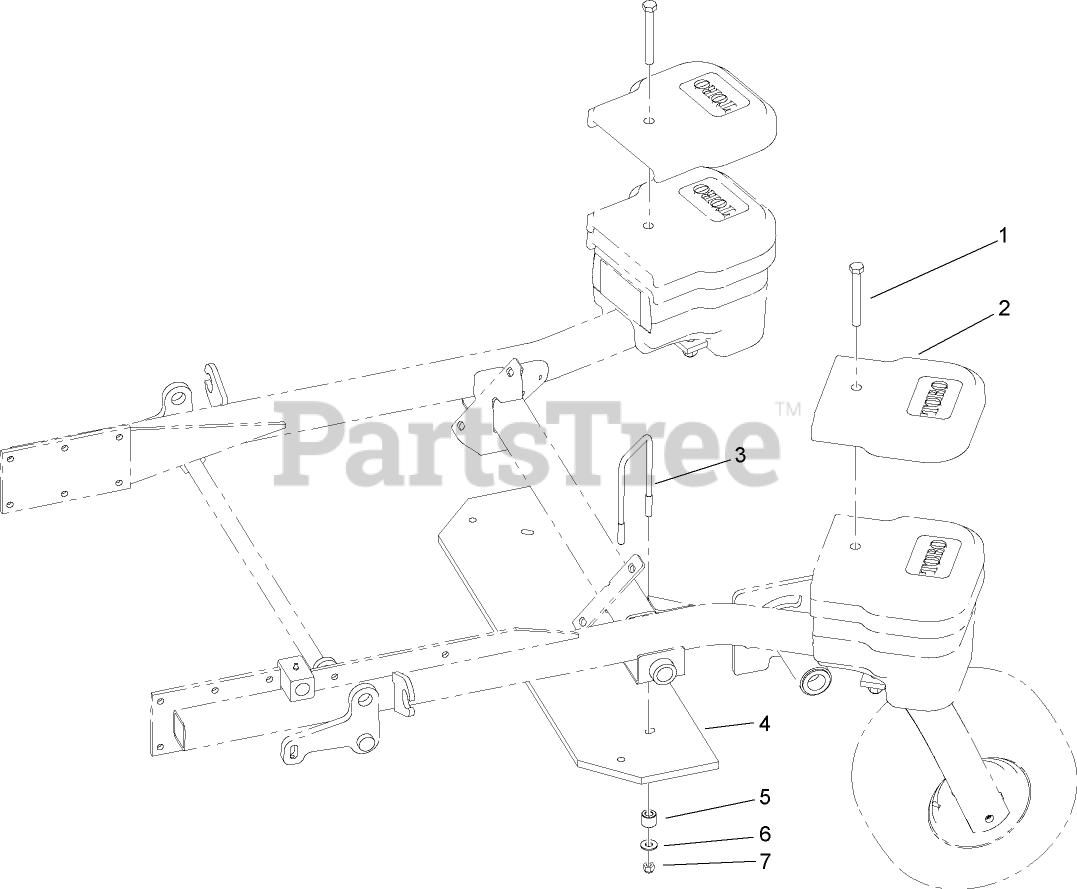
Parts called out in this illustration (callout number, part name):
1	SCREW-HH
2	WEIGHT-TOP
3	U-BOLT
4	BAR-WEIGHT
5	SPACER-BEDBAR
6	WASHER-FLAT
7	NUT-LOCK, NI
